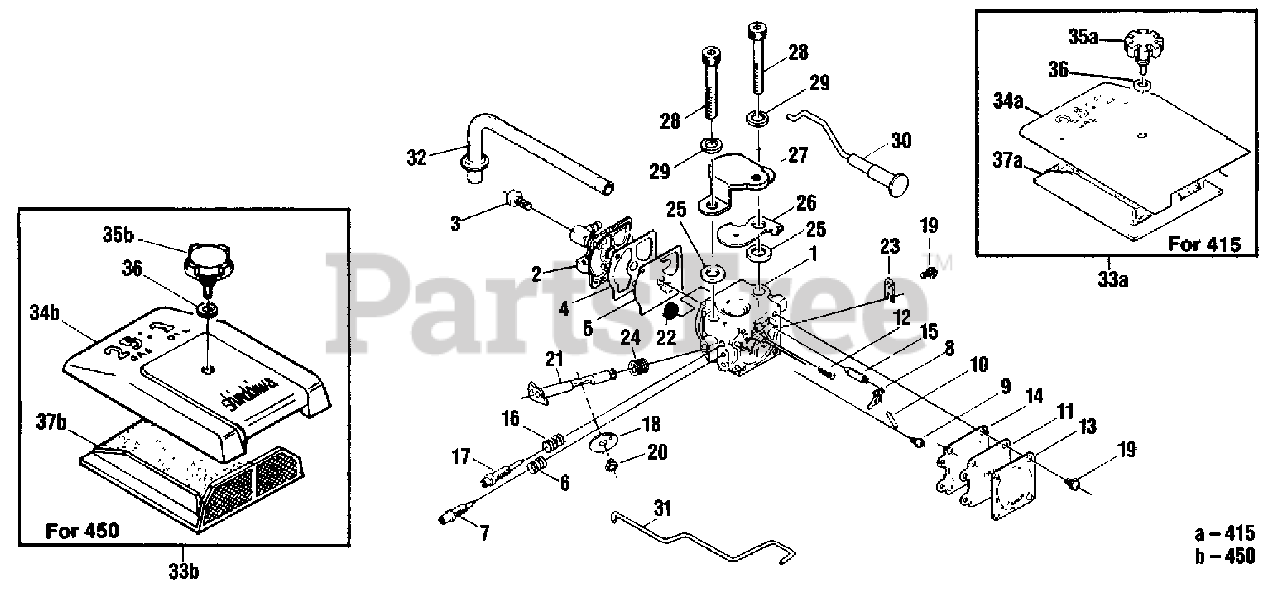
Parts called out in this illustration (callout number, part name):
1	BASE, PURGE
2	COVER ASSY, PUMP
3	SCREW
4	GASKET, PUMP
5	DIAPHRAGM, PUMP
6	SPRING, NEEDLE
7	NEEDLE, LOW SPEED
8	LEVER, METERING
9	SCREW, METERING LEVER PIN
10	PIN, METERING LEVER
11	DIAPHRAGM, METERING
12	SPRING
13	DIAPHRAGM, METERING
14	GASKET, METERING DIAPHRAGM
15	VALVE, INLET NEEDLE
16	SPRING, NEEDLE
17	NEEDLE, HIGH SPEED
18	VALVE, THROTTLE
19	SCREW
20	SCREW
21	SHAFT
22	SCREEN, FUEL INLET
23	CLIP, THROTTLE SHAFT
24	SPRING, THROTTLE RETURN
25	WASHER 5
26	PLATE, CHOKE
27A	BRACKET
27B	BRACKET, CARBURETOR
28	BOLT 5×40
29	WASHER, SPRING 5
30	ROD, CHOKE
31	ROD, THROTTLE
32	PIPE, PULSE
33A	AIR FILTER COVER ASSY
33B	AIR FILTER COVER ASSY
34A	COVER, AIR FILTER
34B	COVER, AIR FILTER
35A	THUMBSDREW
35B	THUMBSCREW
36	O-RING
37A	FILTER, AIR - FLOCKED
37B	FILTER, AIR - FLOCKED
